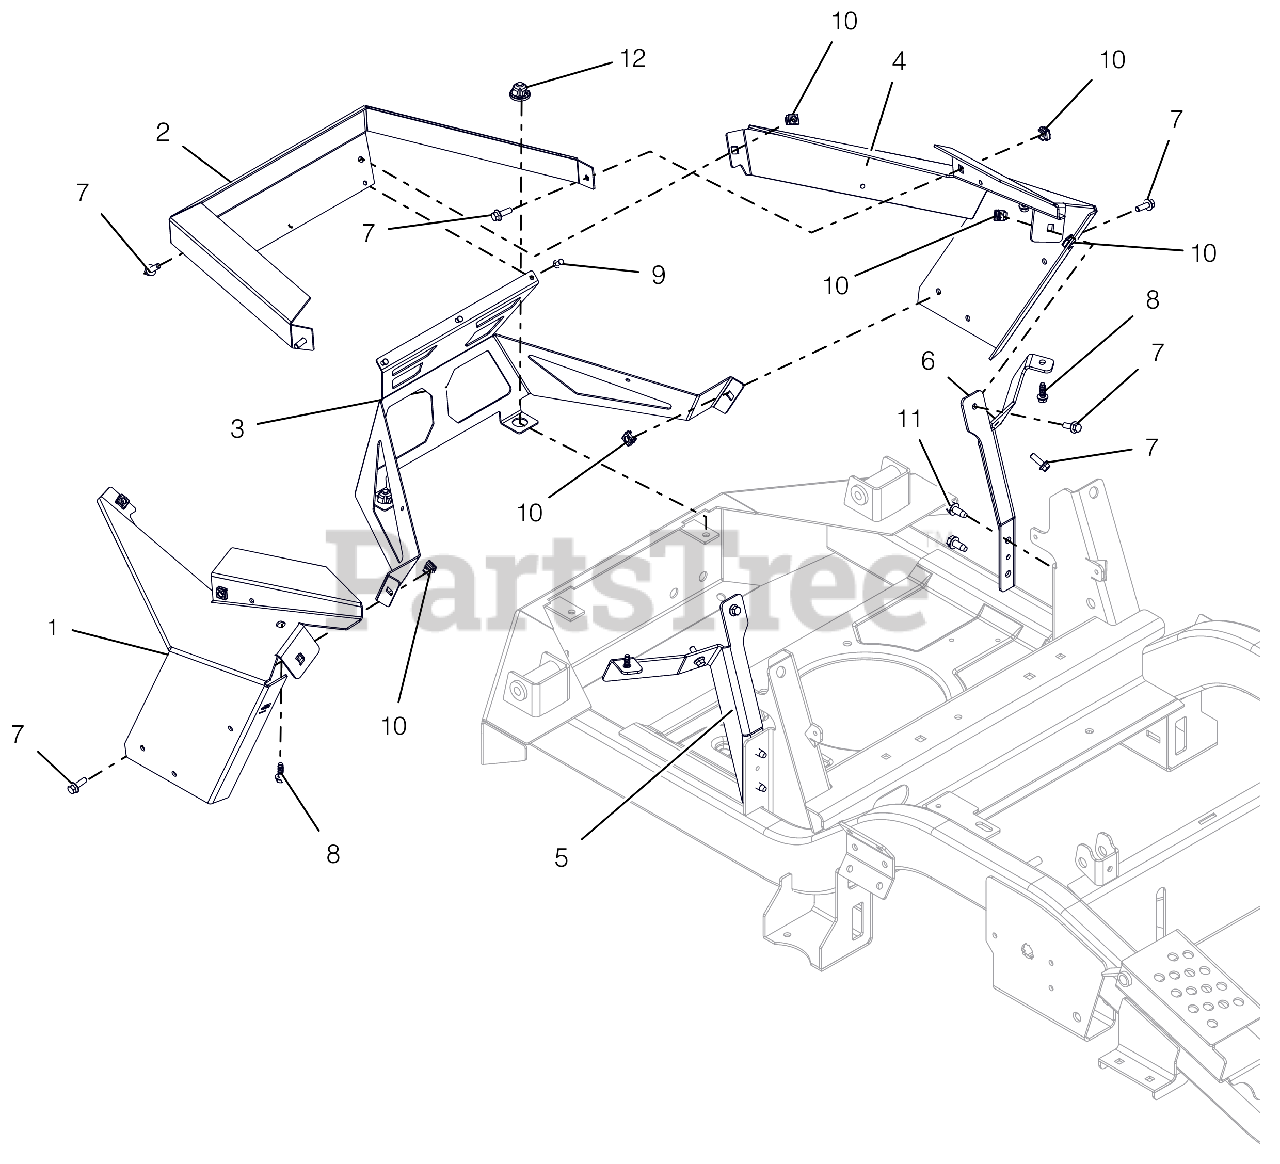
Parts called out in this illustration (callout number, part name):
1	PANEL,RIGHT REAR FENDER MOUNT
2	GUARD,ENGINE WRAP
3	GUARD,ENGINE
4	PANEL,LEFT REAR FENDER MOUNT
5	BRKT, RH FENDER MTG. APEX
6	BRKT, LH FENDER MTG -APEX
7	BLT,HEX-FLG .25-20X.75 G5 BFP
8	SCR-PLASTITE .25-10X.75, YWZC
9	RIVET, #66 STEEL POP PD BLACK
10	NUT RETNR .25-20
11	@SCR-TAP .31-18X.75 HWH TR YWZ
12	GROMMET, 10MM BOLLHOFF
